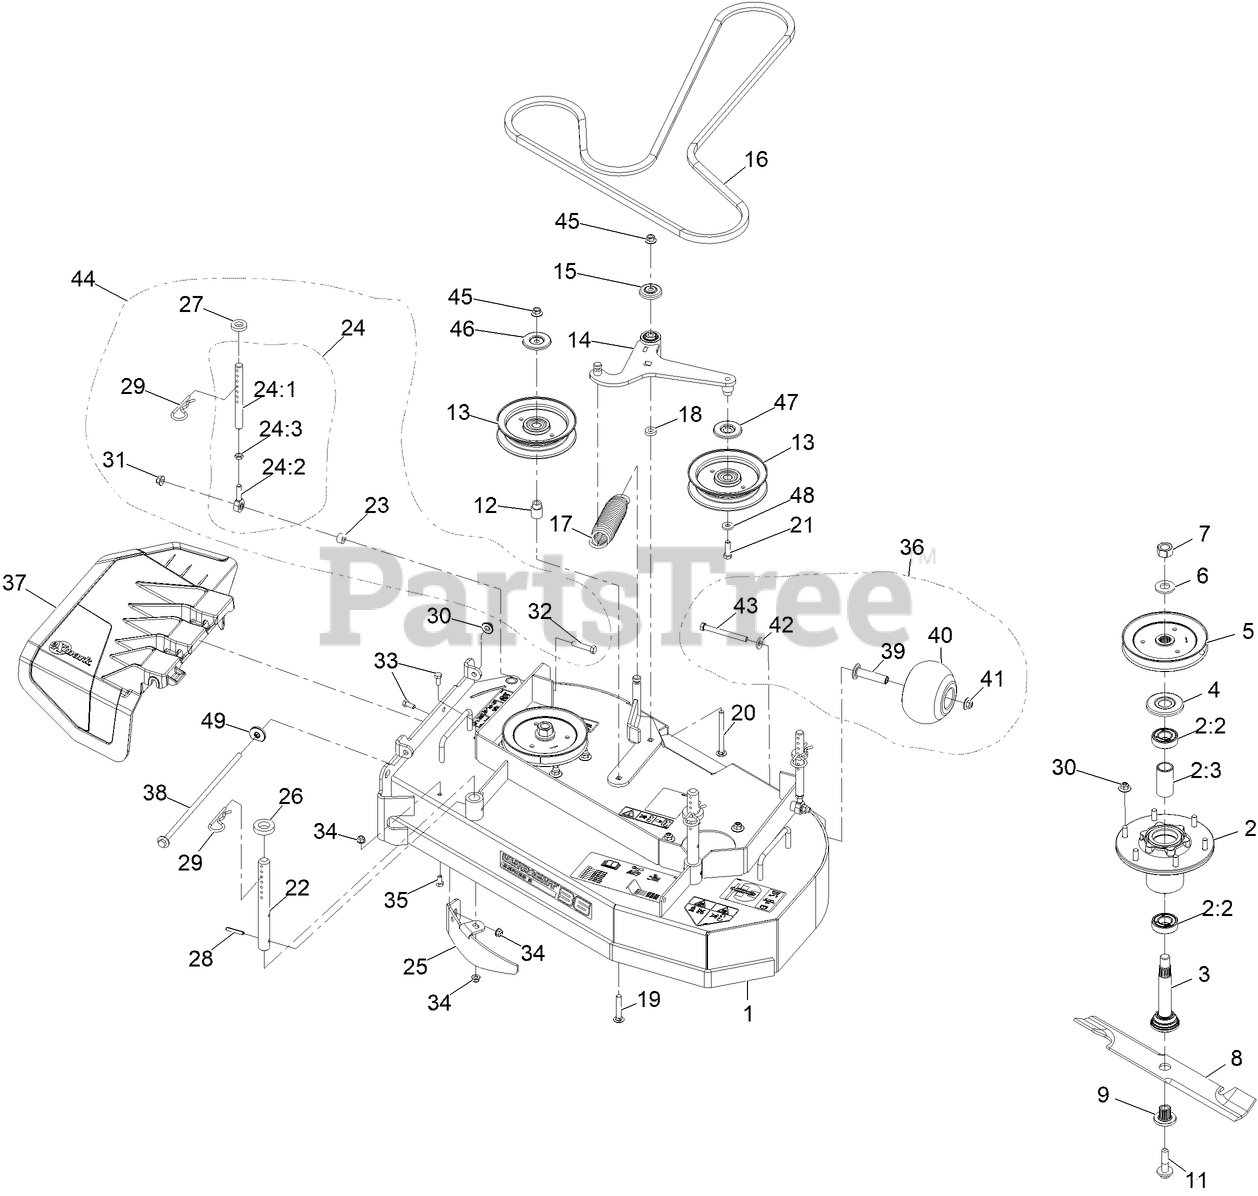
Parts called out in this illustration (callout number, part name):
1	ASM, DECK W/ DECALS, 36
2	ASM-CUTTER HSG WITH BEARINGS
2:2	BEARING-BALL
2:3	SPACER-BEARING
3	ASM-SPINDLE AND SEAL
4	GUARD,BEARING TOP .989
5	SHEAVE,BLADE DRIVE 6.50
7	NUT-HEX
9	BUSHING,SPLINED
11	SCREW,SEMS 1/2-20 X 2.19
12	BUSHING-IDLER
13	IDLER-PULLEY, FLAT
14	ASM-ARM, IDLER
15	GUARD-TOP
17	SPRING-EXTENSION
18	SPACER
19	Bolt-Carriage 3/8-16 X 2 1/4
20	SCREW-CARR
21	SCREW-HH
22	ROD, DECK SUPPORT TTS
24:1	LINK,SUPPORT
24:2	BALLJOINT
24:3	NUT-HJ
25	BAFFLE, DOGLEG
26	SPACER-DECK SUPPORT
29	PIN,HAIR COTTER
30	Nut-Nyloc 3/8-16 Flg
31	NUT-HF, NI
32	SCREW-HH
33	SCREW-HH
34	NUT-HF, NI
35	SCREW-HH
36	KIT, ANTI-SCALP ROLLER
37	Chute-Deck Discharge
38	Pin, Chute
39	AXLE, ROLLER
40	ROLLER-SCALP, ANTI
41	Nut-Nyloc 3/8-16 Flg
42	WASHER-BELLEVILLE
43	SCREW-HH 3/8-16 X 3 3/4 GR 8
44	KIT,SUPPORT LINK W/PIN
46	SHIELD-DUST
47	SHIELD-GUARD, DUST
49	Retainer, Chute
